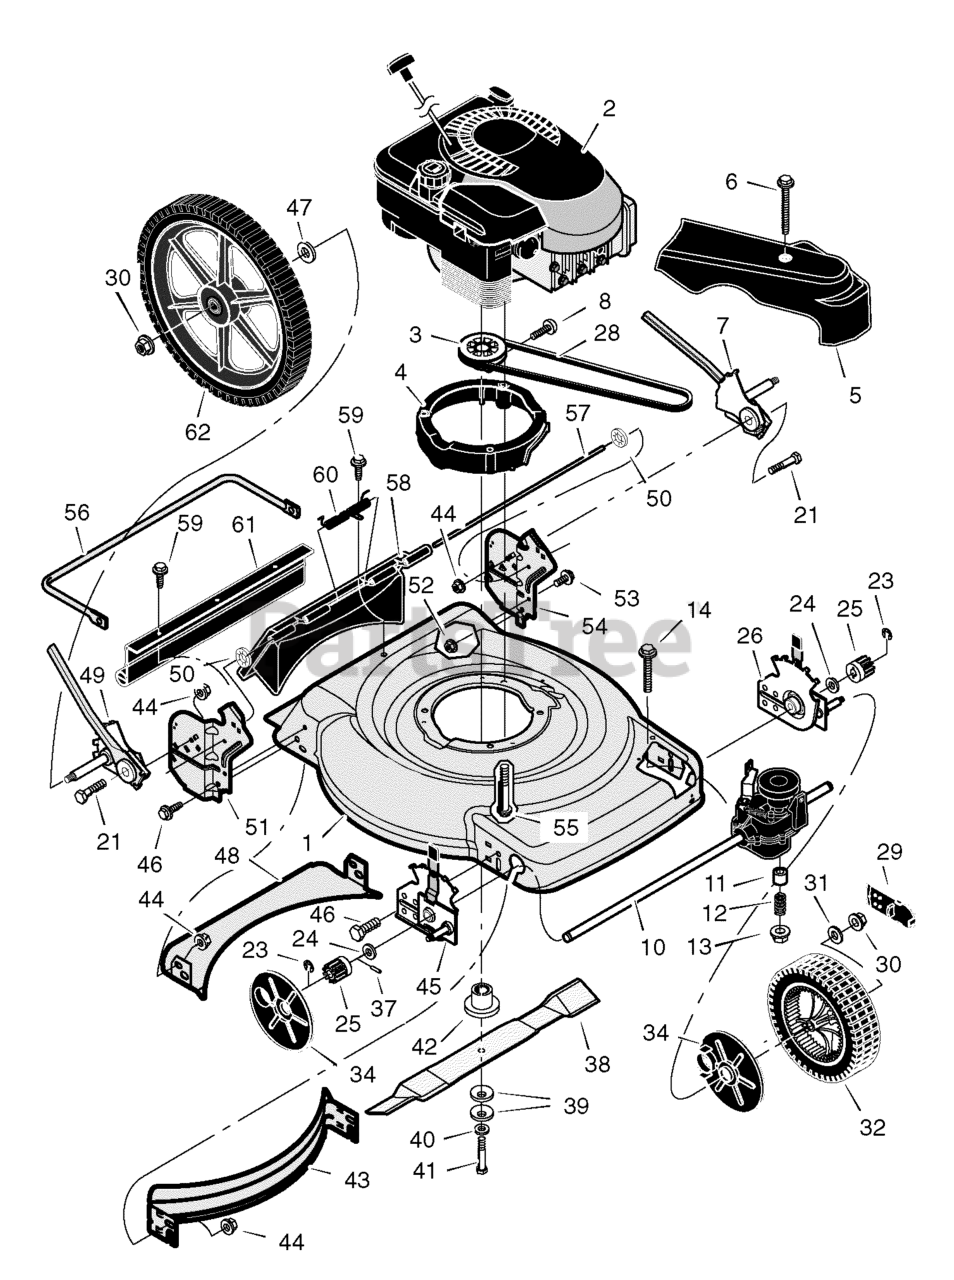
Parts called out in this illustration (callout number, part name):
1	Housing
2	Engine *
3	Pulley, Drive
4	Spacer, Engine
5	Cover, Belt (Black)
5	Cover, Belt (Gray)
7	Adjuster, Left Rear Height
10	Transmission *
11	Spacer
12	Spring, Compression
13	Nut
14	Bolt
23	E-Ring
24	Washer
25	Gear, Pinion
26	Adjuster, Left Front Height
29	Cap, Hub
30	Nut, Flange
31	Washer
32	Wheel & Tire, Front
34	Cover, Dust
37	Pin, Drive
39	Washer, Belleville
40	Washer
42	Adapter, Blade
43	Baffle, Front
44	Nut, Flange
45	Adjuster, Right Front Height
46	Bolt
47	Washer
48	Baffle, Rear
49	Adjuster, Right Rear Height
50	Retainer, Push
51	Bracket, Right Handle
52	Nut, Flange
53	Bolt
54	Bracket, Left Handle
55	Bolt, Engine
57	Rod, Pivot
58	Door, Rear (Black)
58	Door, Rear (Gray)
60	Spring
61	Guard, Rear
62	Wheel & Tire, Rear
